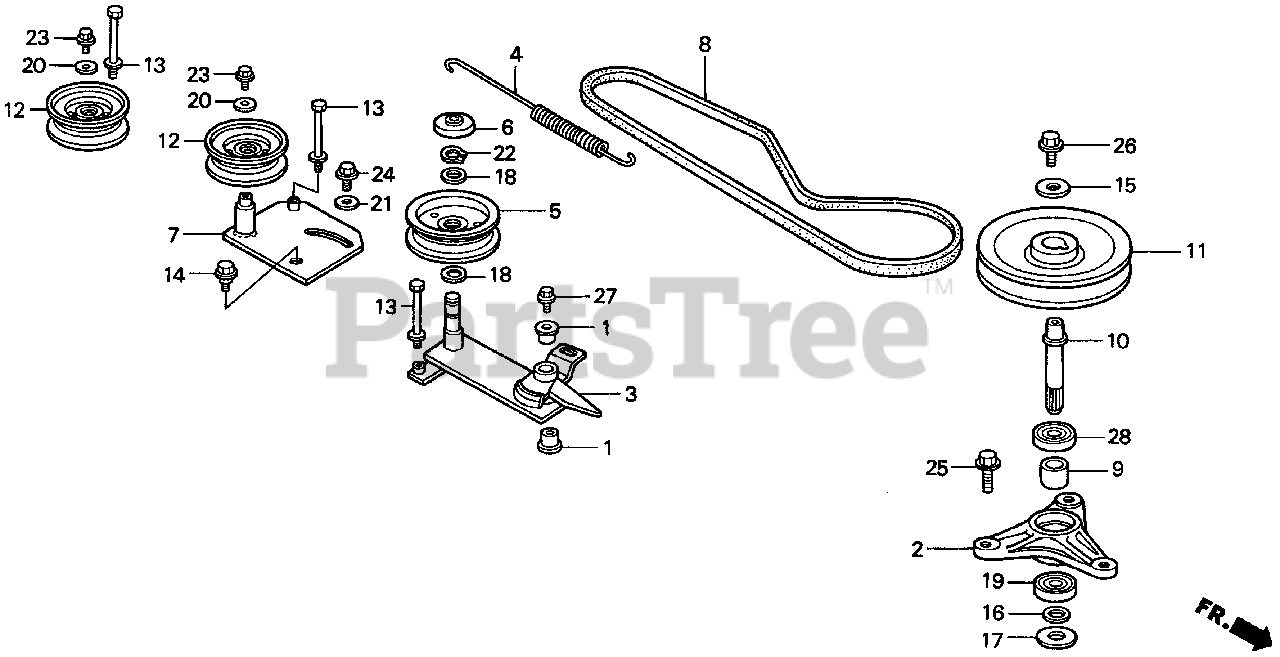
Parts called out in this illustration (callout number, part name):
1	BUSH (15X19X22)
2	HOUSING, BEARING
3	ARM, TENSIONER (DECK)
4	SPRING, TENSIONER ARM
5	ROLLER, TENSIONER (DECK)
6	DUST COVER, TENSION PULLEY (NOT AVAILABLE)
7	ARM, BELT ADJUSTING
8	V-BELT, BLADE (SB-71.2)
9	COLLAR, BLADE SHAFT
10	SHAFT, BLADE
11	PULLEY, CUTTER DECK (120MM)
12	PULLEY, IDLER
13	BOLT, BELT STOPPER
14	BOLT, ADJUSTING ARM
15	WASHER (10.5X27X4)
16	WASHER, THRUST (20MM)
17	WASHER, BLADE HOLDER
18	WASHER (17.3X25)
19	BEARING, RADIAL BALL
20	WASHER, PLAIN (6MM)
21	WASHER, PLAIN (8MM)
22	CIRCLIP (OUTER) (17MM)
23	BOLT, FLANGE (6X12) Use up to Engine SN 1543277.
24	BOLT, FLANGE (8X16) Use from Engine SN 1000016.
25	BOLT, FLANGE (10X28)
26	BOLT, FLANGE (10X16) (NA USE ALT:95700-10016-08)
27	BOLT, FLANGE (6X12) Use from Frame SN 1001725.
28	BEARING, RADIAL BALL (6204UU)
